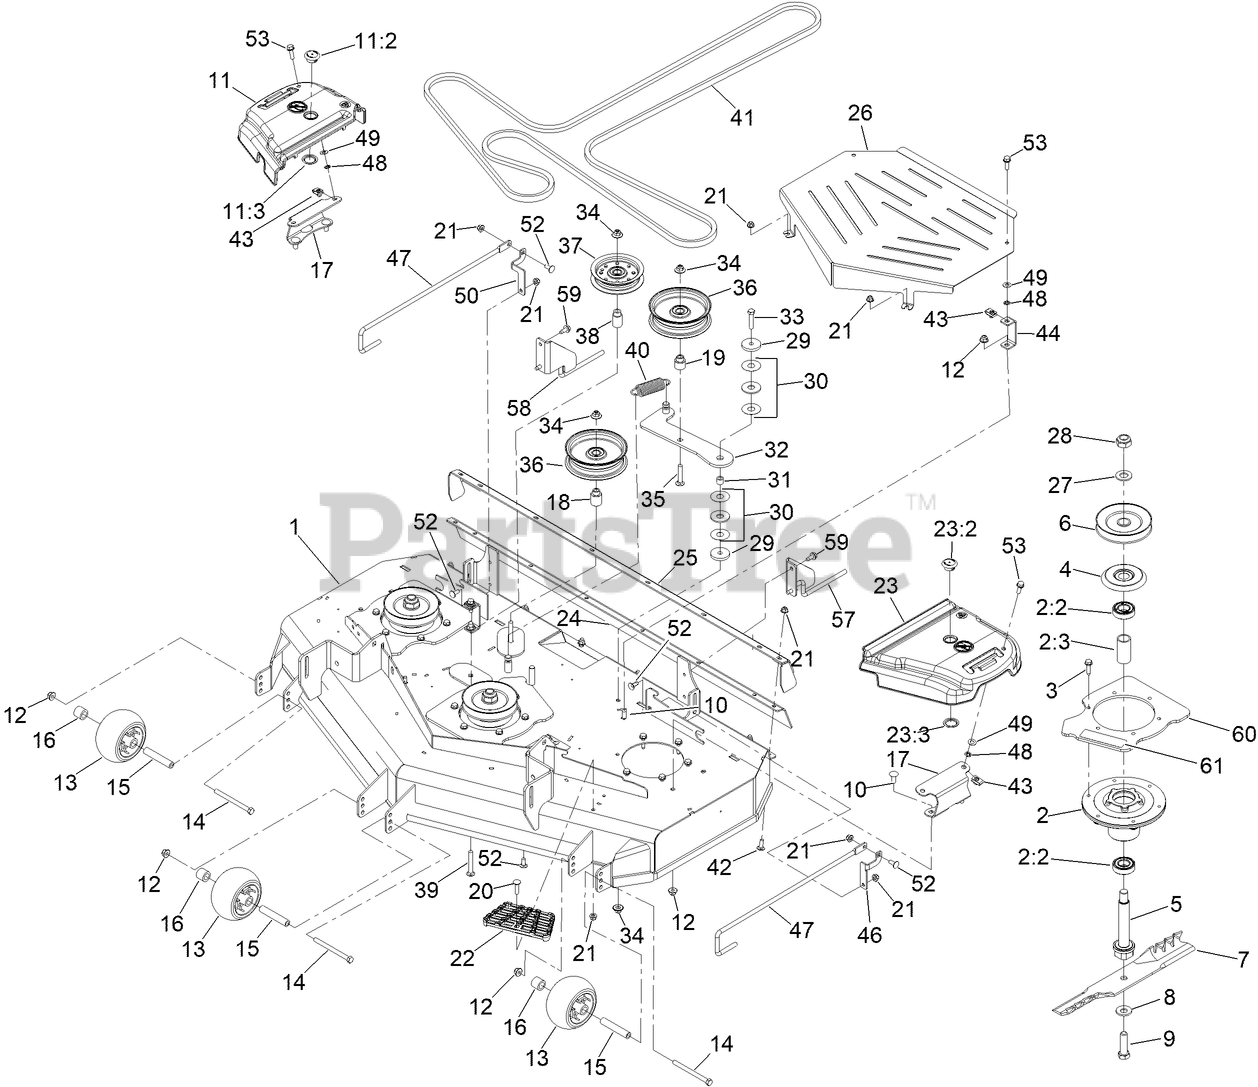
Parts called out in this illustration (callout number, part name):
1	DECK DECAL ASM
2	SPINDLE ASM
2:2	BEARING-BALL
2:3	SPACER-BEARING
3	SCREW-HWHTF
4	SHIELD-BEARING
5	SHAFT-SPINDLE
6	PULLEY
7	BLADE-ROTARY, ATOMIC 16.5
8	WASHER-BELLEVILLE
9	SCREW-BLADE
10	SCREW-CARR
11	RH BELT COVER ASM
11:3	RING-RETAINING
12	NUT-HF, NI
13	ROLLER-SCALP, ANTI
14	SCREW-HH
15	TUBE-SPANNER
16	TUBE-SPACER
17	BRACKET-COVER, BELT
18	BUSHING-IDLER
19	BUSHING-IDLER
20	SCREW-CARR
21	NUT-HF, NI
22	STEP-DECK
23	LH BELT COVER ASM
23:3	RING-RETAINING
24	DEFLECTOR
25	BRACKET-DEFLECTOR
26	GUARD-CENTER BELT 48 (RD)
27	WASHER
28	NUT-LOCK, NI
29	WASHER-PLAIN
30	WASHER-FRICTION, COMPOSITE
31	BUSHING-LEVER, LIFT
32	ARM-IDLER
33	SCREW-HH
34	NUT-FLANGE, NI
35	SCREW-CARR
36	IDLER-PULLEY, FLAT
38	BUSHING-IDLER
39	SCREW-CARR
40	SPRING-EXTENSION
41	BELT, DECK DRIVE
42	BOLT-CARR
43	NUT-U
44	BRACKET-GUARD
46	BRACKET-MOUNT, REAR (LH)
47	ROD-SUPPORT, LOWER
48	NUT-PUSH
49	WASHER-THRUST
50	BRACKET-MOUNT, REAR (RH)
52	SCREW-CARR
53	SCREW-HHF
57	SUPPORT-LOWER, LH
58	SUPPORT-LOWER, RH
59	SCREW-HWHTF
60	SUPPORT, SPINDLE [SERVICE]
61	DECAL-COVER, MISSING
